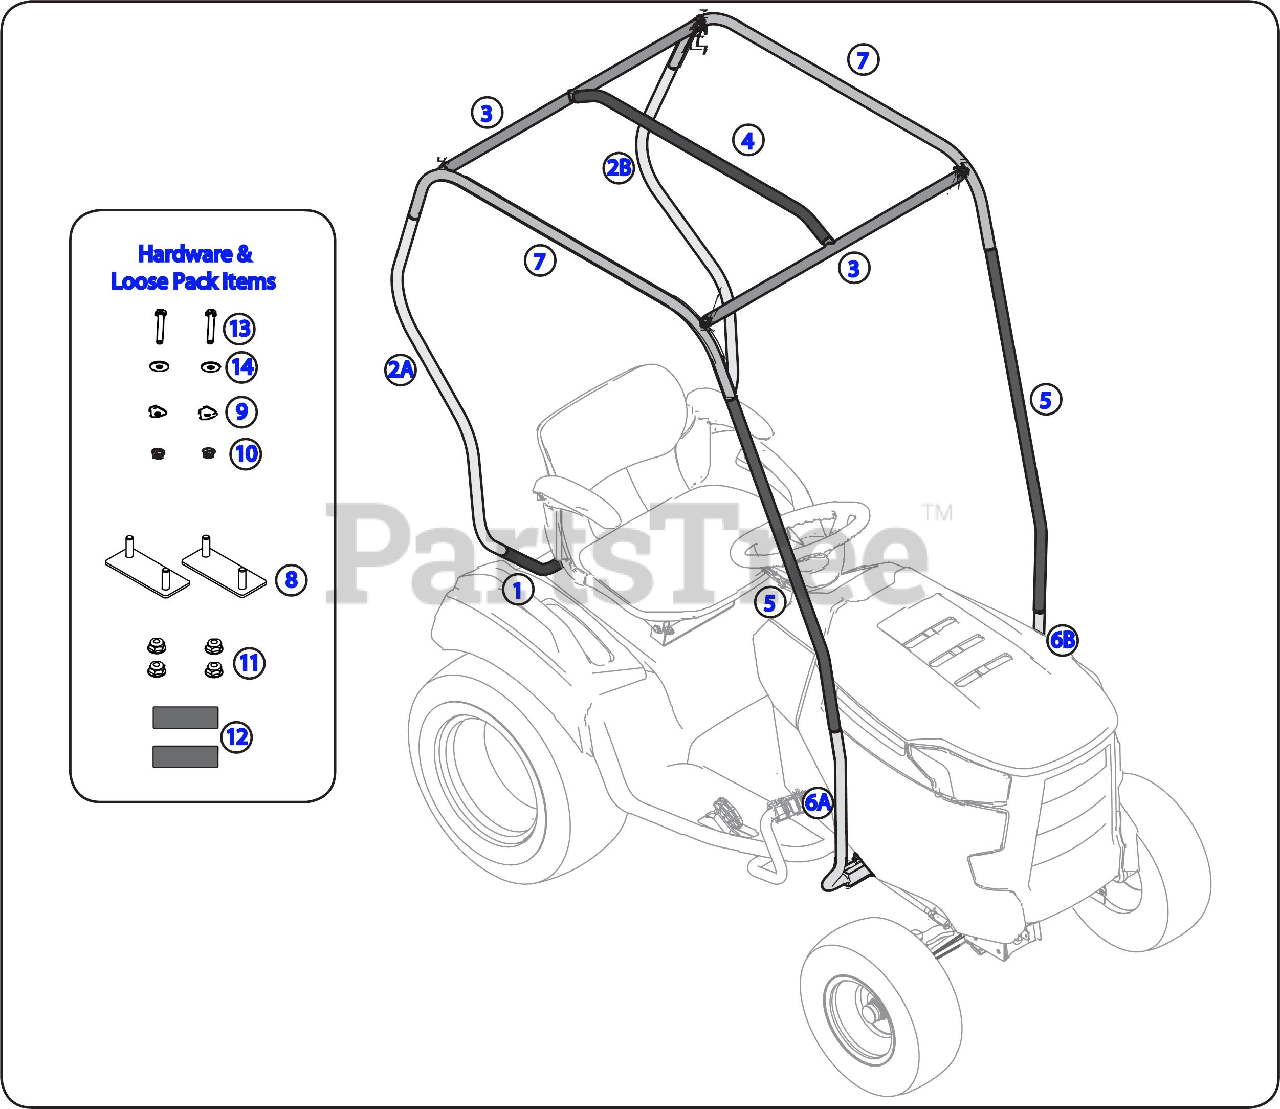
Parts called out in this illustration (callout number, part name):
1	Rear Support
2A	Rear Right Support
2B	Rear Left Support
3	Cross Support
4	Center Support
5	Front Support
6A	Front Right Support
6B	Front Left Support
7	Side Support
8	Front Canopy Mount Plate
9	Sdle. Washer., .320 x .930 x .060
10	Flange Lock Nut, 5?16-18
11	Flange Lock Nut, 1?4-20
12	Reflector Labels
13	Hex Screw, 5?16-18 x 1.75
14	Fl. Wash., 344 x 1.000 x .063
NS	Spring Button Clip
NS	Snow Cab
NS	Sun Shade
